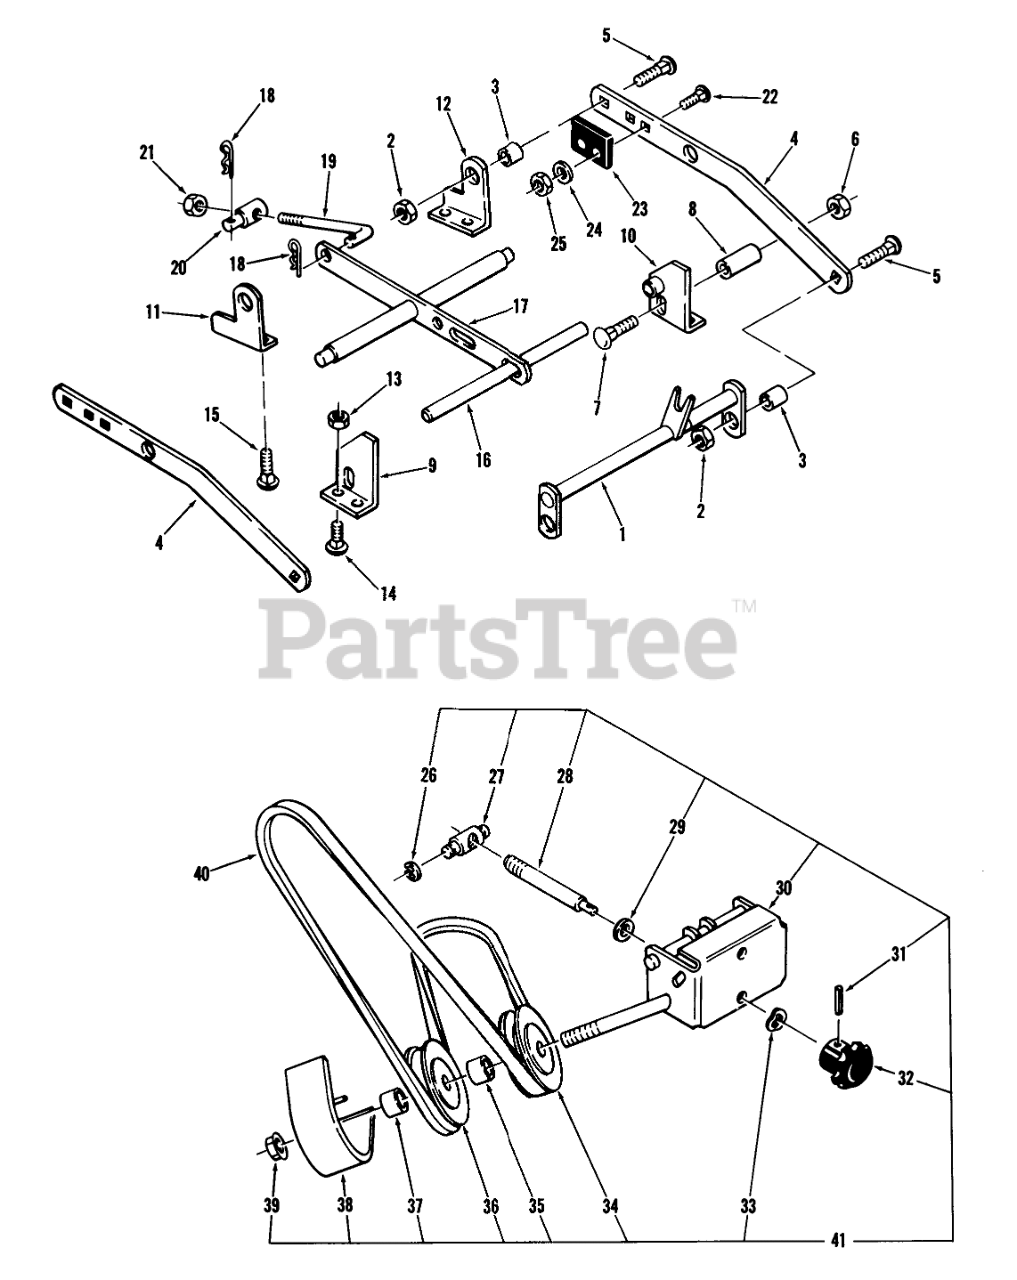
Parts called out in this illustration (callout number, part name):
1	Hitch
2	LOCKNUT-FLANGE
3	SPACER
4	Bar Draft
5	Bolt
6	Nut
7	CARRIAGE BOLT -4
8	SPACER-BEARING
9	Front Bracket RH
10	Front Bracket LH
11	R.H. Rear Bracket
12	Engine 7 H.P. Electric
13	Nut
14	Bolt-Carriage
15	Bolt
16	Front Shaft
17	Leveler
18	Hairpin
19	ROD-LEVEL ADJUST
20	TRUNNION-LIFT
21	NUT
22	Bolt-Carriage
23	BUMPER
24	Collar
25	Nut
26	E Ring-3/8
27	TRUNNION-DOUBLE
28	ROD ADJ
29	Washer
30	Front Support
31	PIN-ROLL
32	KNOB-ADJUSTMENT
33	Spring Washer
34	Pulley-V
35	SPACER
36	PULLEY-FLAT IDLER
37	SPACER-OUTER
38	Belt Cover
39	Nut 3/4-16 MF
40	V-BELT
41	ASM-SUPPORT,IDLER
